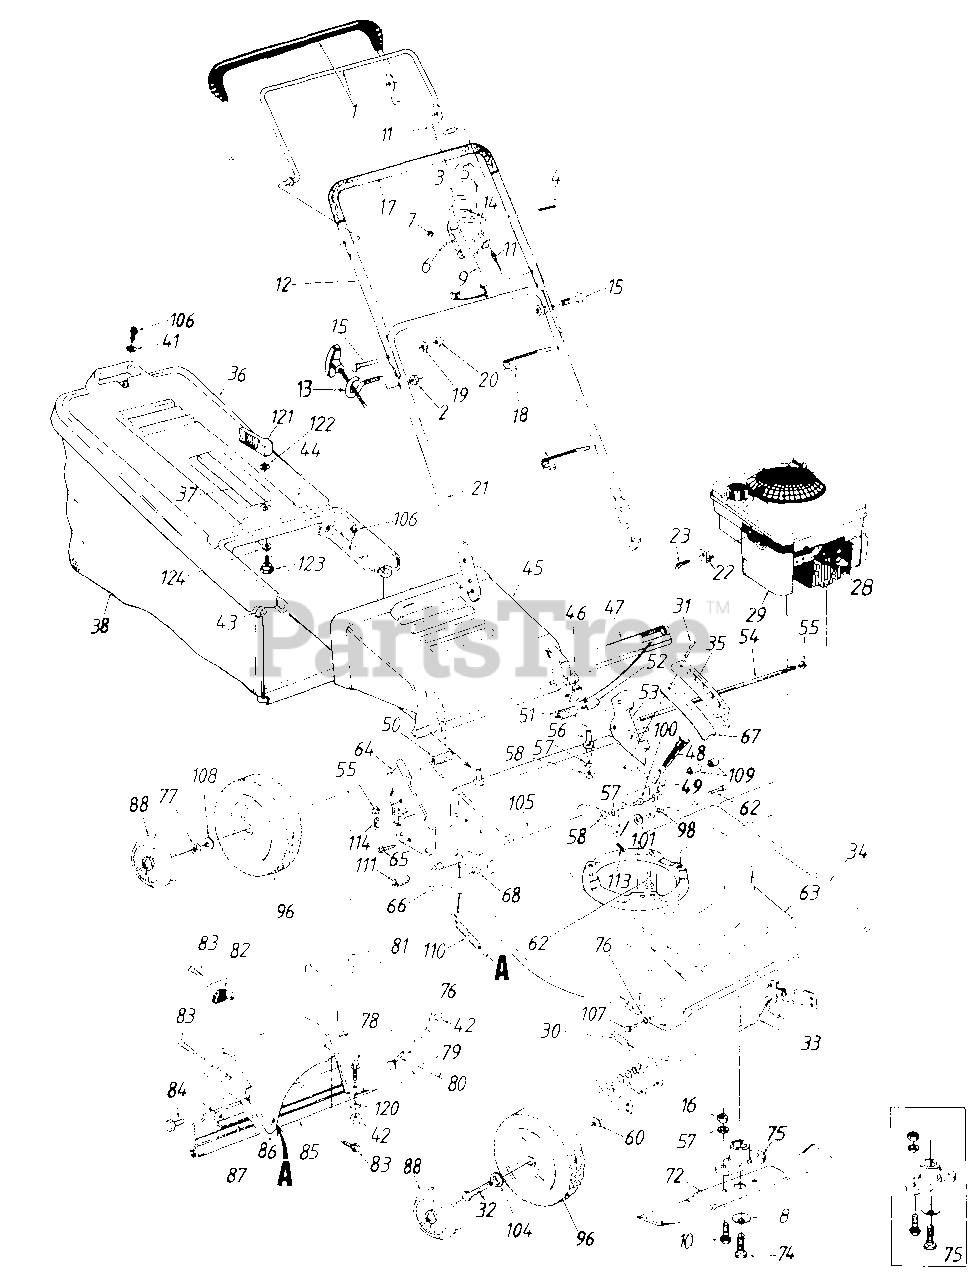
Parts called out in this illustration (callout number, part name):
1	Control Handle
2	Hex L-Nut 1/4-20 Thd.
3	Throttle Body
4	Oval C-Sunk Mach. Scr.
5	Throttle Box Comp.
6	Spr. Wash..66" I.D.
7	Hex L-Nut 1/4-20 Thd.
8	Bell-Wash..39" I.D.
9	Throttle Control Wire - 55"
10	Hex Bolt 3/8-24 x 1" Lg.
11	Control Cable - 40.5"
14	Throttle Lever
15	Curved Carriage Bolt 5/16-18 x 1.38" Lg.
16	Hex Nut 3/8-24 Thd.
17	Foam Grip
18	Cable Tie
19	L-Wash. 5/16" I.D.
20	Hex Nut 5/16-18 Thd.
21	Lower Handle
22	Cable Clamp
23	Wash. Hd. Scr. #10-32 x .62" Lg.
28	Spark Plug Boot
29	Engine
30	Extension Spring 2.39" Lg.
31	Torx Hd. AB-Tap Scr. 1 4" x .62" Lg.
32	Axle Bolt
34	Height Adj. Connecting Rod
35	Height Adjustment Plate
36	Hardtop Bag Cover
37	Hardtop Handle
38	Grass Bag
41	Fl-Wash..281" I.D. x .62" O.D.
42	Hex Nut 1/4-20 Thd.
44	Rear Catcher Frame
45	Chute Deflector
46	Deflector Plug
47	Seal - Extrusion
49	Spring Lever
50	Torsion Spring - R.H.
51	Torsion Spring - L.H.
52	Spacer .255" I.D.
53	Handle Brkt. Ass'y.- L.H.
54	Hinge Pin 17.75" Lg.
55	Cap Speed Nut 56
56	Shld. Pin 3/8-24 x 1.43" Lg.
57	L-Wash. 3/8" I.D.
58	Hex Jam Nut 3/8-24 Thd.
60	Bell-Wash..38" I.D. x .88" O.D.
62	Hex L-Wash. Hd. Scr. 3/8-16 x 1" Lg.
63	21" Deck Ass'y.
64	Handle Brkt. Ass'y.- R.H.
65	Hex L-Wash. Hd. AB-Tap Scr. 1/4 x .62" Lg.
66	Hex Wash. Hd. Tap Scr. 3/8-16 x .75" Lg.
67	Height Adjustment Support
68	Spacer .385" I.D.
72	21" Blade
74	Hex Bolt 3/8-24 x 1.5" Lg.
75	Blade Adapter Kit
76	L-Wash. 1/4" I.D.
77	Hex Ins. Top L-Nut 3/8-16 Thd.
78	Hex Bolt 1/4 20 x .85" Lg.
79	Rear Belt Baffle
80	Carr. Bolt 1/4-20 x .50" Lg.
83	Torx Mach. AB-Tap Scr. 1/4 x .62" Lg.
84	Hex B-Tap Scr. 1/4 x .38" Lg.
85	Rear Flap
96	Wheel Ass'y. Comp.
98	Shld. Spacer .50" Dia.
100	Shld. Pin 3/8-24 x 1.43" Lg.
101	Fl-Wash..375" I.D. x 1.0"
104	Wave Wash..51" I.D. x .75"
105	Rear Axle Ass'y.
106	Hex L-Wash. AB-Tap Scr. 1/4 x .62" Lg.
107	Hex L-Wash. Hd. AB-Tap Scr. 1/4 x .38" Lg.
108	Fl-Wash. 385" I.D. x 87"
109	Spacer .526" I.D.
110	Extension Spring 3.8" Lg.
111	Sleeve .526" I.0.
113	Cotter Pin 3/32" Dia. x .75"
114	Internal Cotter Pin 5/16" Dia.
120	Bell-Wash. 1/4" I.D.
121	Grass Catcher Locking Knob
122	Internal L-Wash. 1/4" I.D.
123	Shld. Bolt .342" Dia. x .268"
124	Wave Washer 3/8" I.D.
